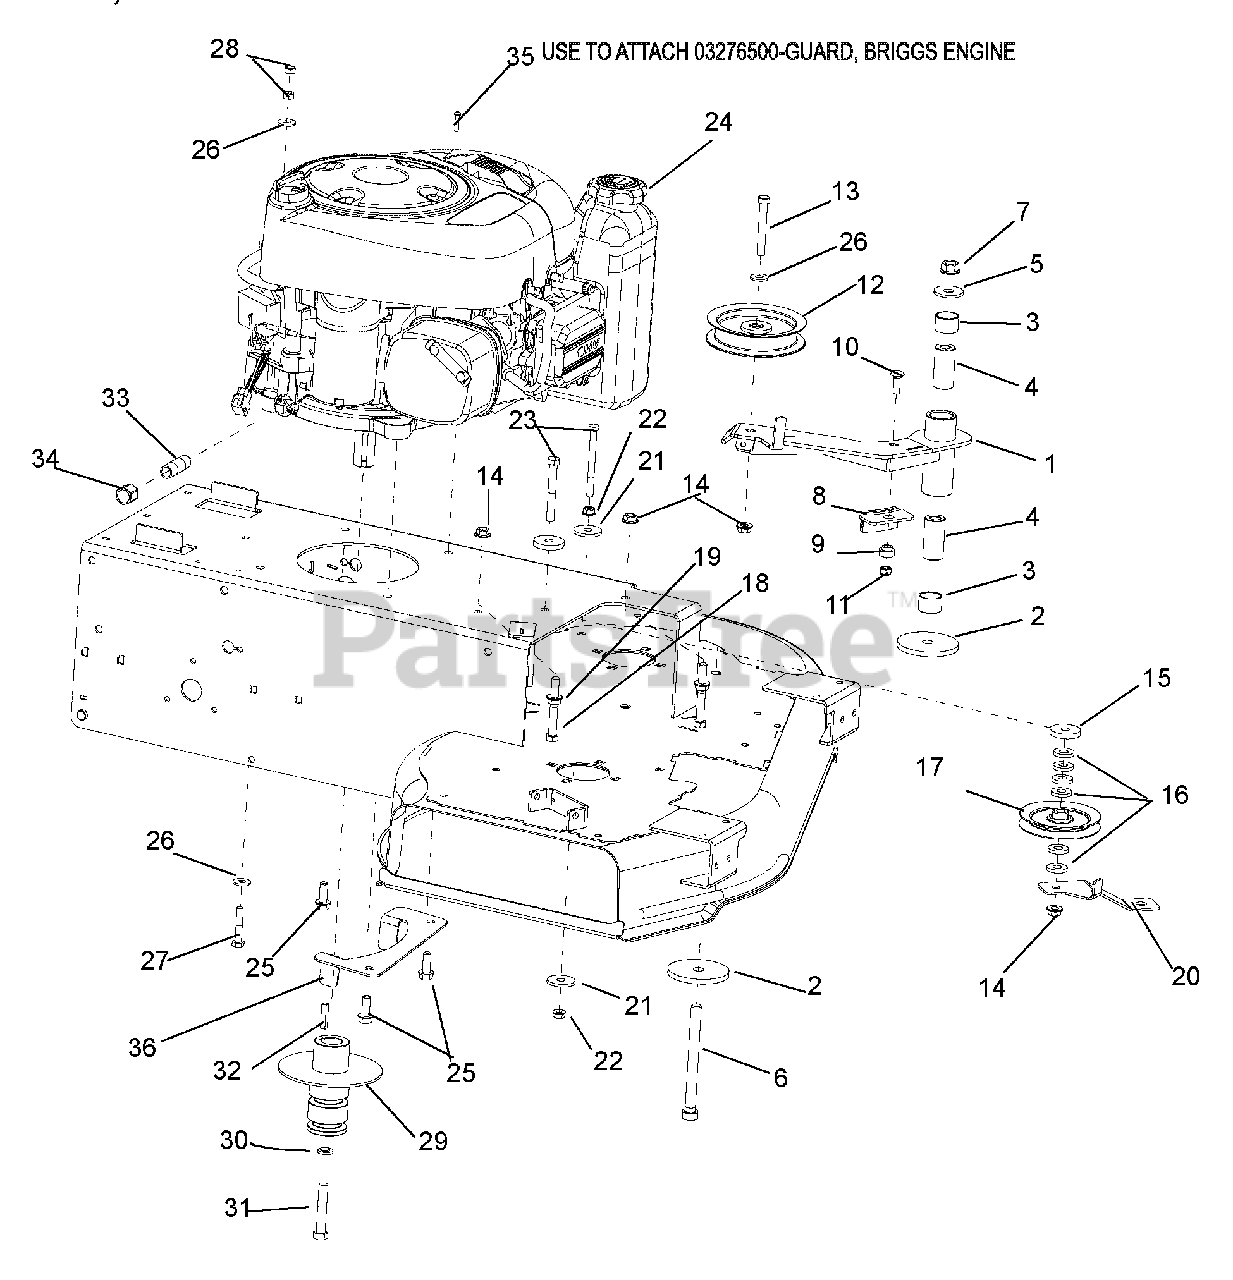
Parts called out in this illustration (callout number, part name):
1	Weldment Arm, PTO Idler
2	Washer, Flat .531 x 3.00 x .25
3	Bearing 1.00 x 1.12 x .75
4	Bushing, Spacer .505/.500 x .999/.996 x 2.05/2.03
5	Washer, Flat Steel .511 x 1.44 x .125
6	Bolt, Hex .50-13 x 5.50
7	Nut, Locking Top Flange .50-13
8	Assembly, Brake Pad
9	Bushing, Flange
10	Bolt, Round Head Square Neck .31-18 x 1.00 Grade 5
11	Nut, Locking Nylon .312-18
12	Idler, Flat .38 x 4.00 x 1.06
13	Bolt, Hex .38-16 x 2.75
14	Nut, Locking Top Flange .38-16
15	Washer, Flat Steel .406 x 1.50 x .245
16	Washer, Flat Steel .43 x 1.00 x .160
17	Idler, 4.00 x .38
18	Bolt, Hex .38-16 x 3.00
19	Nut, Flange .375-16
20	Bracket, Idler Brace
21	Washer, Flat Steel .406 x 1.375 x .135
22	Nut, Spin-Lock Flange .312-18
23	Bolt, Hex .31-18 x 3.50
24	Engine, 10.5 h.p. 49-State (404)
25	Screw, Hex Washer Head Tapping .38-16 x 1.00
26	Washer, Flat Steel .38 x .875 x .083
27	Bolt, Hex .31-18 x 1.75
28	Nut, Locking Center .31-18
29	Pulley, Deck Drive
30	Washer, Locking .44 x .109
31	Bolt, Hex .44-20 x 2.50
32	Key, Square .25 x 1.25 x .25
33	Nipple, Black Pipe .38 x 2 (SN 000101 - 000609)
34	Cap, Black Pipe .38 (SN 000101 - 000609)
35	Screw, 8-16 x .87 Pan Head 3-Lobe
36	Bracket, Belt Finger
